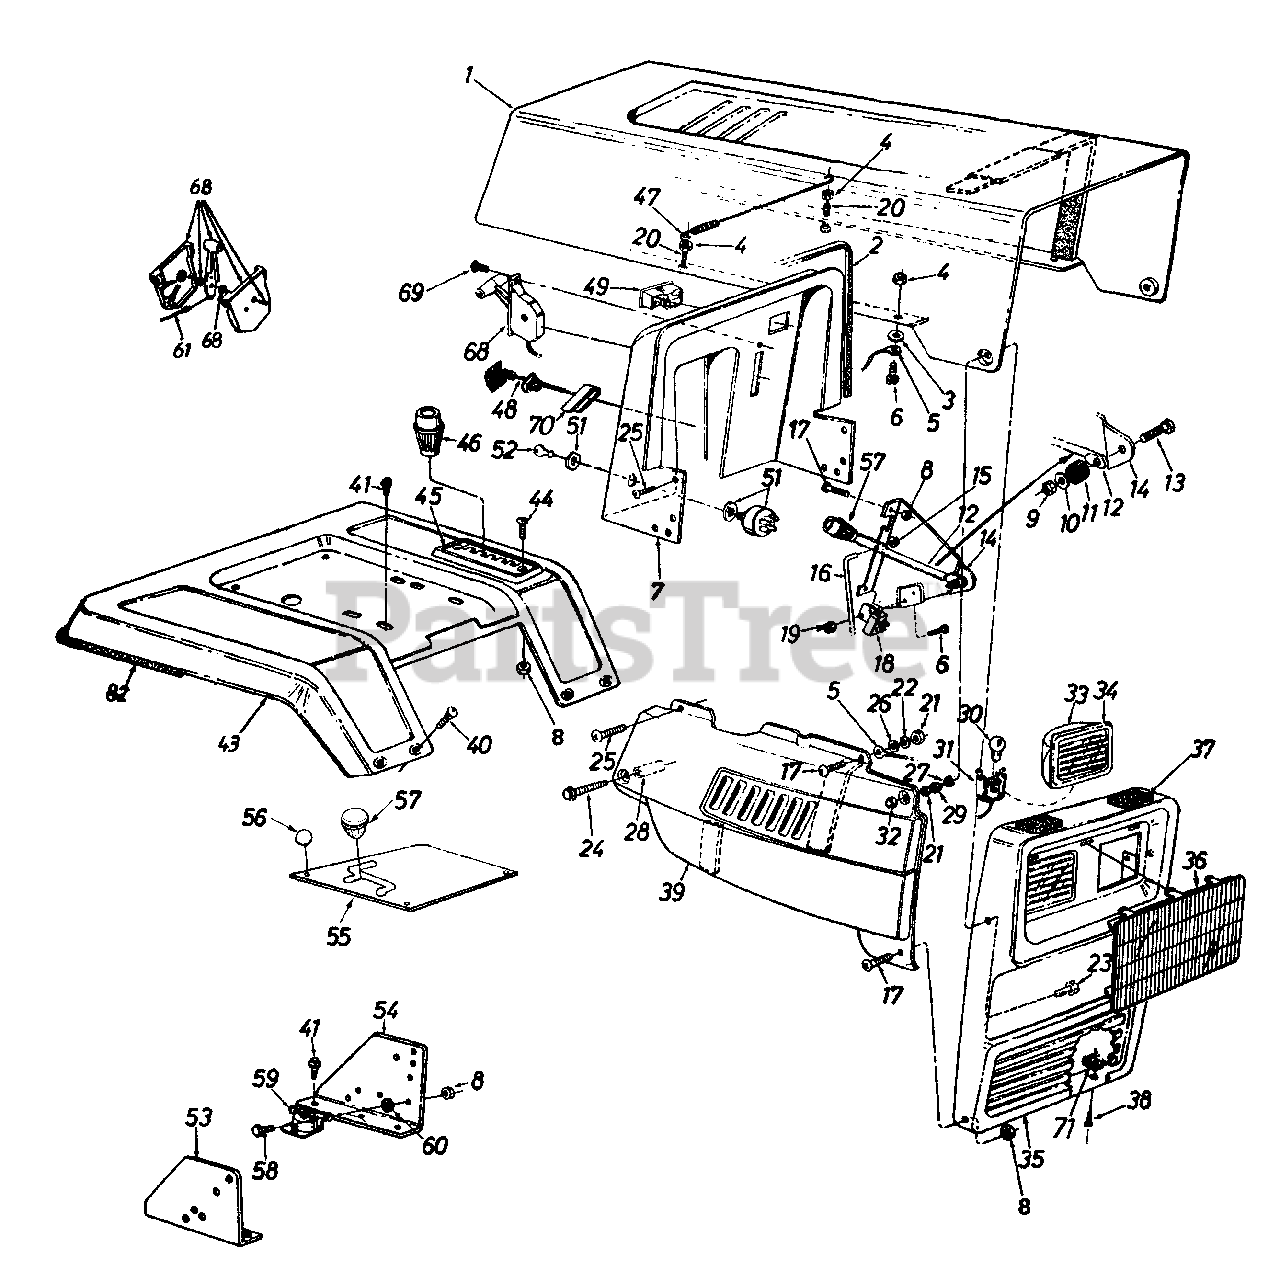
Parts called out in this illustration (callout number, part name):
3	Fl-Wash. .188" I.D. x .41" O.D.
4	Hex Sems Nut #10-24 Thd.
5	Hood Stop
6	Truss Mach. Scr. #10-24 x .5" Lg.
9	Hex L-Nut 1/4-20 Thd.
10	Fl-Wash. .281" I.D. x .73" O.D.
11	Rubber Washer
12	PTO Lever
13	Hex Bolt 1/4-20 x 1.25" Lg.
16	Deck Control Rod
17	Truss Mach. Scr. 1/4-20 x .5" Lg.
18	Safety Switch
19	Hex Sems Nut #10-24 Thd.
20	Hex Bolt 10-24 x 1.0" Lg.
21	Hex Nut 1/4-20 Thd.
22	L-Wash, 1/4" I.D.
23	Hex Bolt 1/4-20 x .88" Lg.
24	Hex Wash. TT-Tap Scr. 1/4-20 x 1.75" Lg.
25	Hex TT-Tap Scr. 1/4-20 x .75" Lg.
26	Fl-Wash, .25" I.D, x .62"
27	Spr. Wash. .39" I.D. x .62"
28	Spacer .26" I.D. x .375"
29	Shld. Spacer .375" Dia. x .125" Lg.
30	Lamp
31	Socket
32	Acorn Nut 1/4-20 Thd.
33	Headlight Housing
34	Headlight Lens
37	Foam Strip
38	Hex Bolt 5/16-18 x .75" Lg.
41	Hex Wash. AB-Tap Scr. 5/16 x .75" Lg.
45	6-Speed Selector Plate
46	Shift Knob
47	Hood Spring
48	Choke Control 46" Lg.
49	Ammeter
51	Ignition Switch
52	Ignition Key
57	Knob--Blade Clutch
58	Hex Bolt 1/4-20 x .5" Lg.
59	Solenoid
60	Ext. L-Wash. 1/4" I.D.
61	Throttle Wire 35" Lg.
68	Throttle Control Box Ass'y.
69	Truss Mach. AB-Tap Scr. #10 x .5" Lg.
70	Retainer Clip
71	U-Nut 5/16-18 Thd.
82	Trim Strip 81" Lg.
